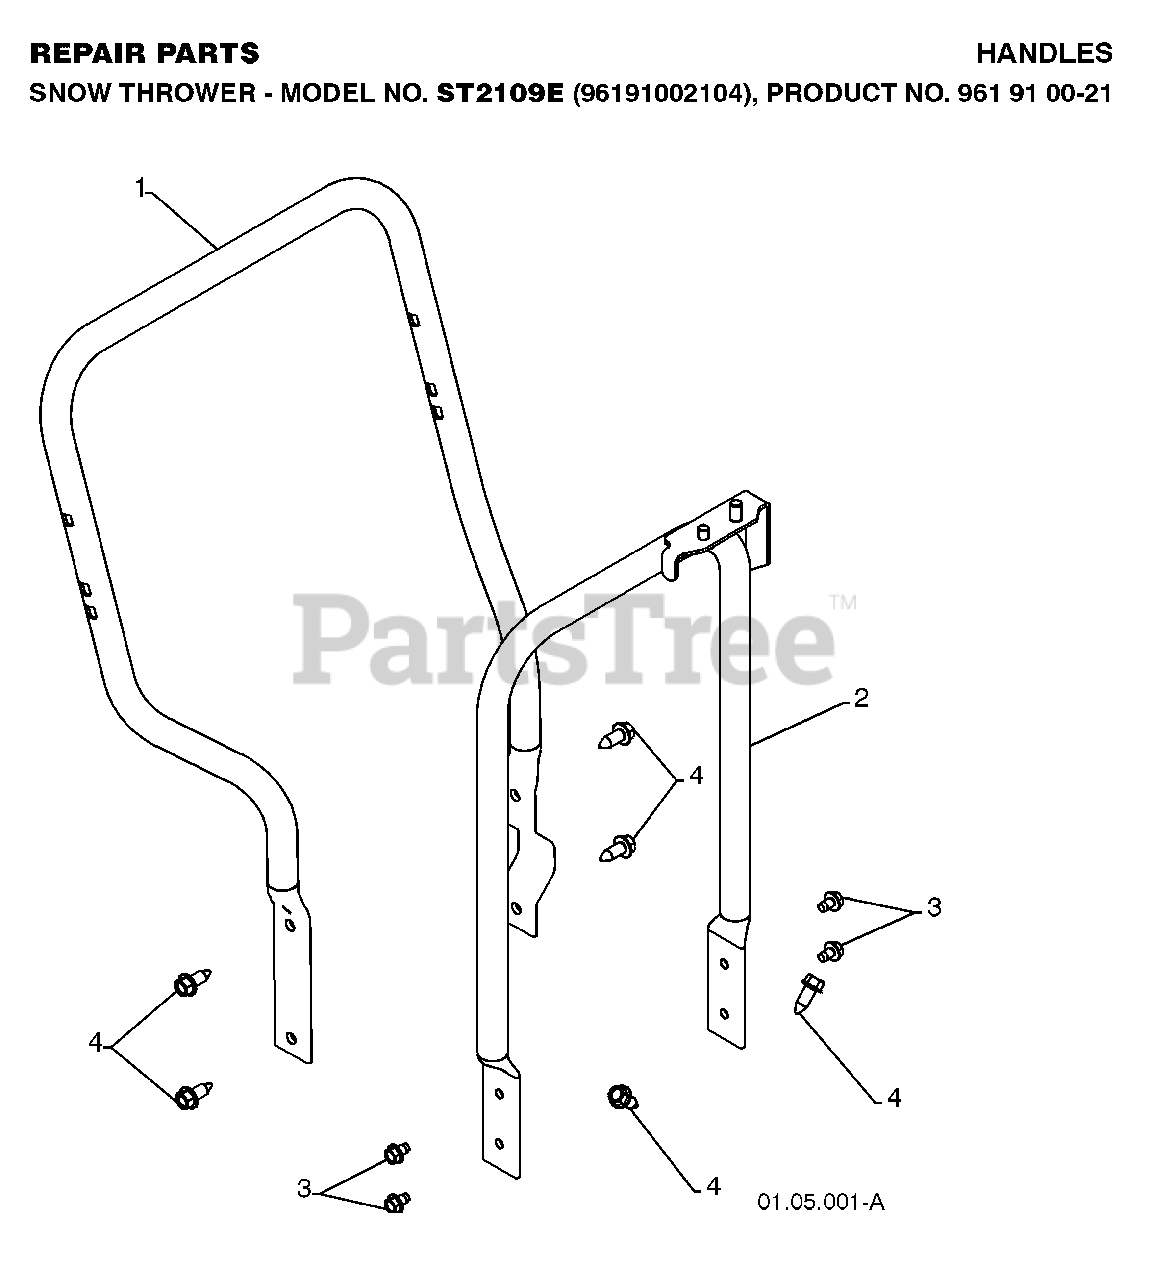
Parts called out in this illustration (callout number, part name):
1	TUBE.LOWER.BLACK
2	SUPPORT, PIVOT
4	SCREW 3/8-16X1
